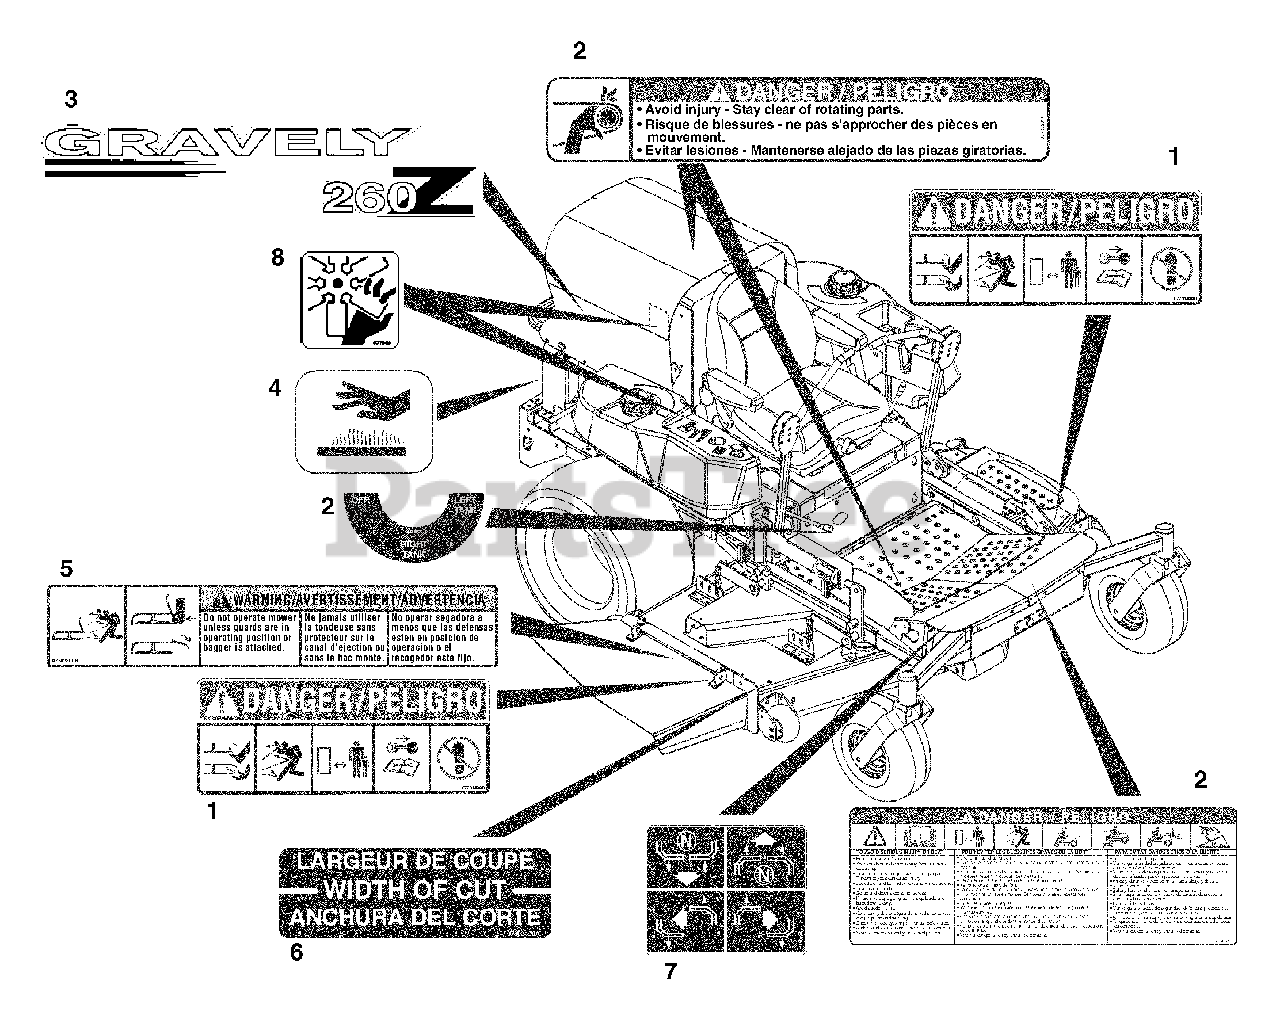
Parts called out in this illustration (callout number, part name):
1	Decal, Mower Pan Head Danger
2	Set, Decal-Common Danger/Fuel
3	Decal, PM-260Z Hood (036, 038, 309)
3	Decal, PM-272Z Hood (037, 039)
4	Decal-Hot Surface
5	Decal, Warning
6	Decal, Width of Cut
7	Decal-Instructional
8	Decal, Danger Fan
